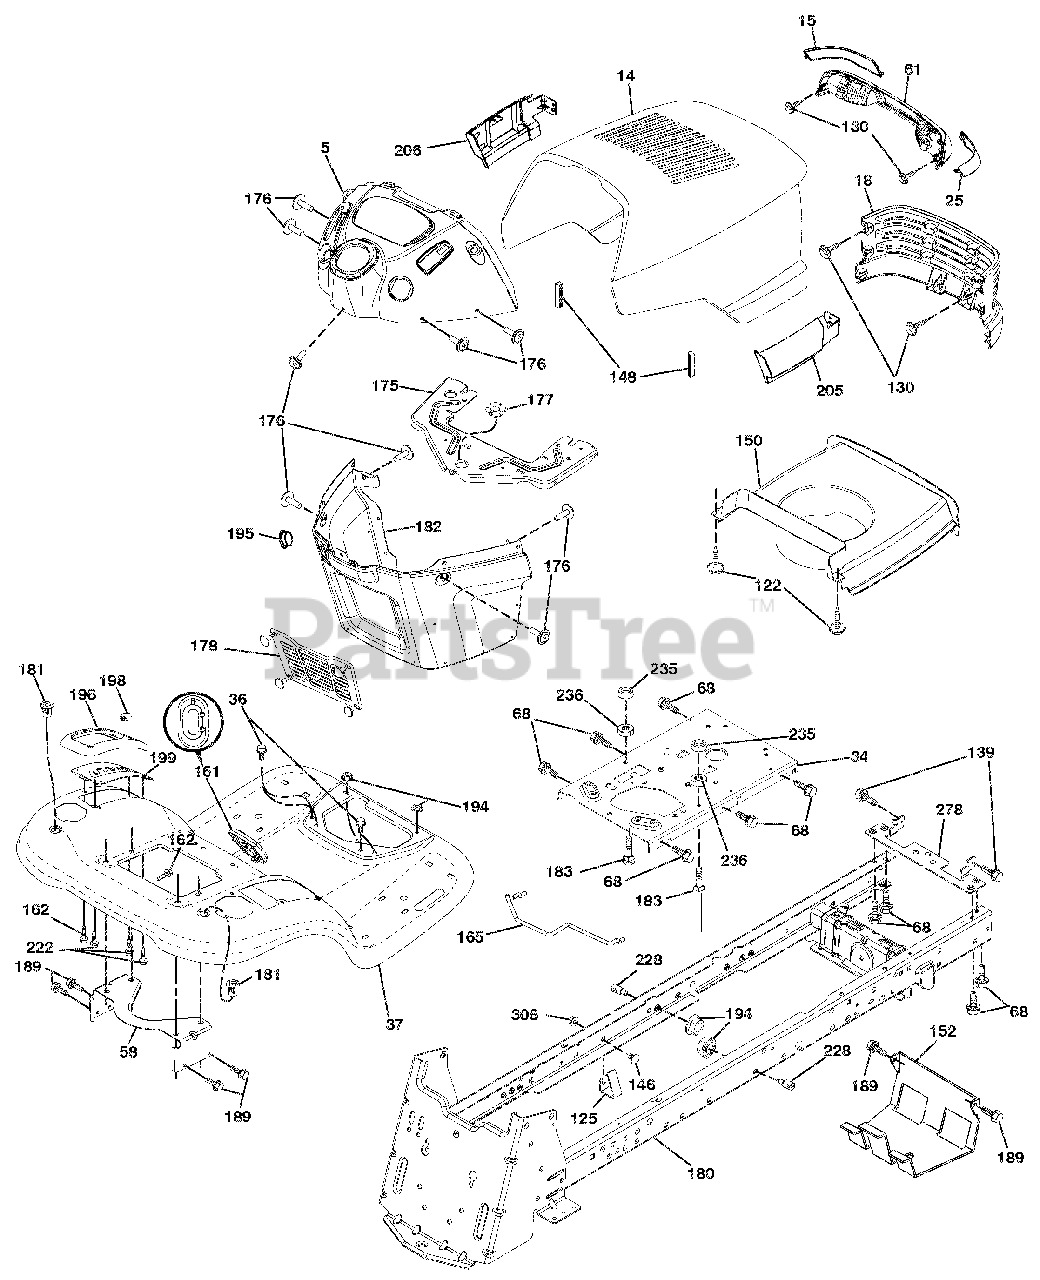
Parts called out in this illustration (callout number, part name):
15	LENS ELITE ARIENS BLACK
25	LENS ELITE HUSQ CLEAR RH
34	PLATE.ENGINE.WELDED.CHASSIS
36	SCREW.5/16-18X3/4.SMGML.TAP/R
58	FENDER SUPPORT BRACKET
61	ASM LIGHT BOX
68	SCREW.THDROL.5/16-18 X 1/2TYTT
122	SCREW TO 32 X 5/8
125	CLIP.FUEL.LINE
139	BOLT SHOULDER 5/16-18
148	BUMPER HOOD LARGE 1.75
150	DUCT AIR ENGINE
152	SHIELD.BROWNING.W/TEX
161	CONSOLE FUEL WINDOW
162	SCREW.HEX.WSH.HI-LO.1/4X1/2UNC
165	SUPPORT.TANK.REAR.W/TEX
175	CROSSMEMBER LT
176	SCREW.#10-24X5/8.RND.QUDRX.GIM
177	BUSHING.STEERING.YT/GT
178	CARGO ASM NET
180	CHASSIS
181	BUSHING MNT FEND CRGO BLK TEX
182	DASH TOWER LT CCS
183	BOLT.FIN.HEX.5/16-18 UNC X1-1/
189	SCREW.5/16-18X3/4.SMGML.TAP/BL
194	Nut, Lock Hex Flange 5/16-18 u
195	PLUG HOLE DASH TOWER
196	CONSOLE ASM. DECK LIFT
198	INDICATOR DECK LIFT
199	PLATE DECK LIFT
205	SKIRT SIDE RH
206	SKIRT SIDE LH
222	SCREW.THD.ROLL.1/4-20 X 5/8
228	STUD.FASTNER.W/'D'ANTI-ROTATIO
235	SPACER.FENDER
236	NUT.CENTER LOCK.5/16-18 UNC
278	X-PIECE HOOD
306	Nut, Hex, Flangelock 3/8-16
